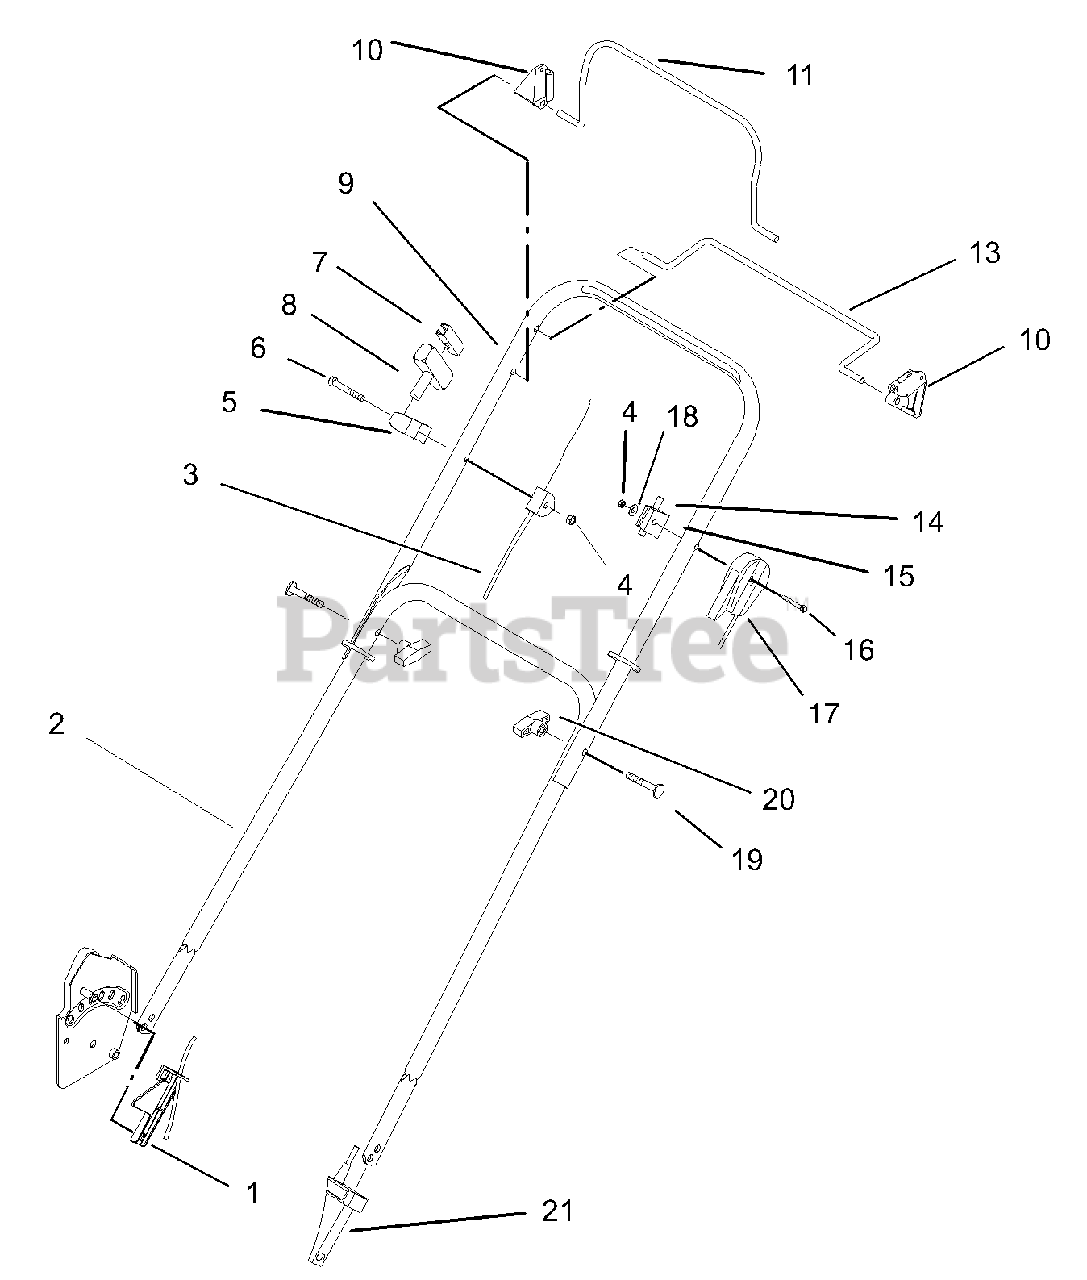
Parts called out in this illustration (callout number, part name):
1	GUARD-CABLE
2	HANDLE-LOWER
3	CABLE-BRAKE
4	NUT-LOCK, NI
5	GUIDE-ROPE
6	SCREW-HH
7	CLIP-STARTER
8	HANDLE-START
9	HANDLE-UPPER
10	STOP-PIVOT
11	BAIL-BRAKE
13	BAIL-CONTROL
14	CABLE-GROUND SPEED
15	ANCHOR-CABLE, UPPER
16	SCREW-HH
17	THROTTLE CONTROL ASM
18	WASHER-FLAT
20	KNOB-HANDLE
21	ANCHOR-CABLE
